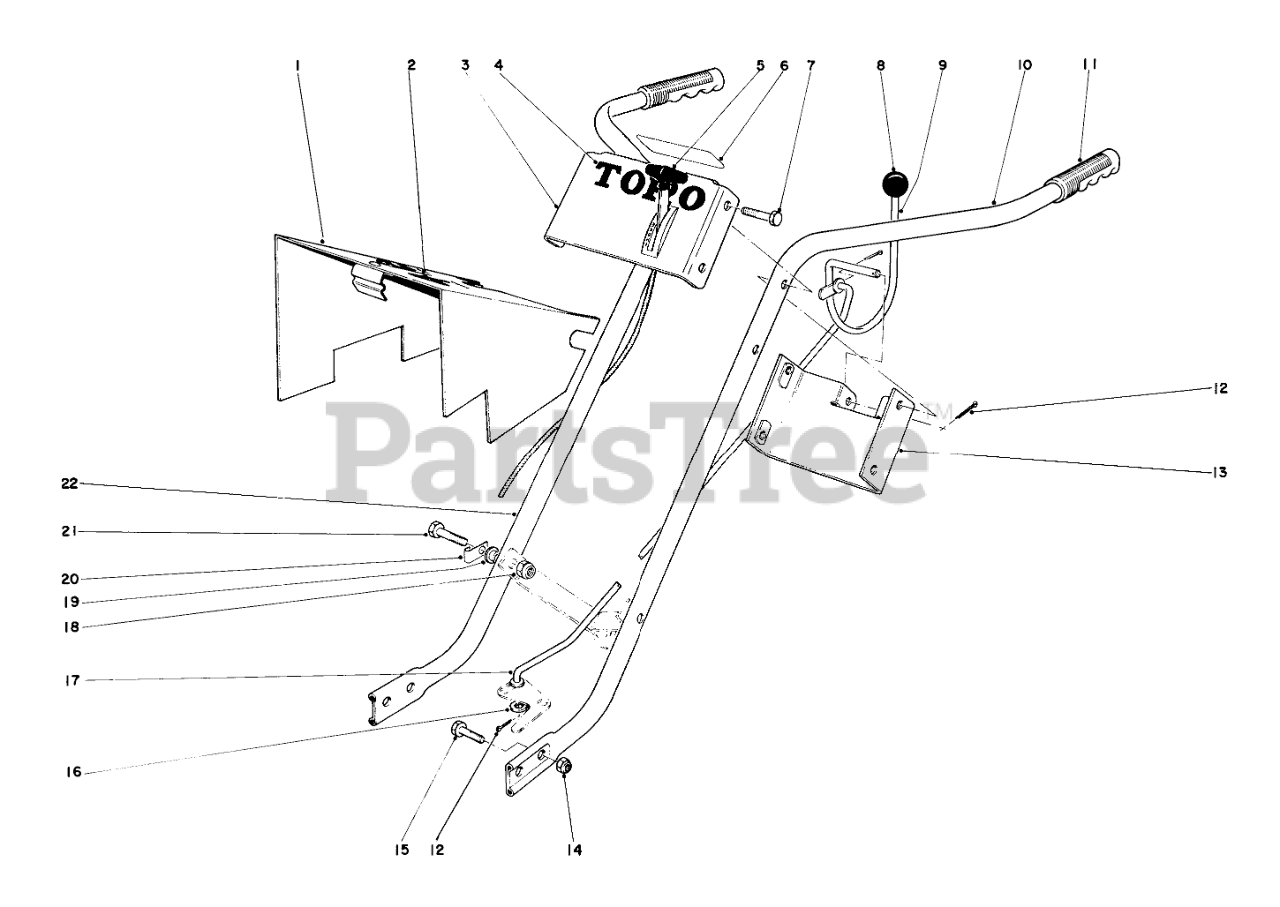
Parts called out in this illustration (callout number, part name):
1	Pulley Cover
2	Decal (42)
3	Control Plate
4	Decal, Toro
5	Throttle Assy.
6	Decal Clutch
7	SCREW-HH
8	KNOB-CONTROL
9	Clutch Control
10	Handle L.H.
11	Handle Grip
12	PIN-COTTER
13	Handle Brace
14	NUT-LOCK, CONE
15	SCREW-HH
16	WASHER-FLAT
17	Clutch Rod
18	NUT-LOCK, CONE
19	Spacer
21	SCREW-HH
22	Handle R.H.
